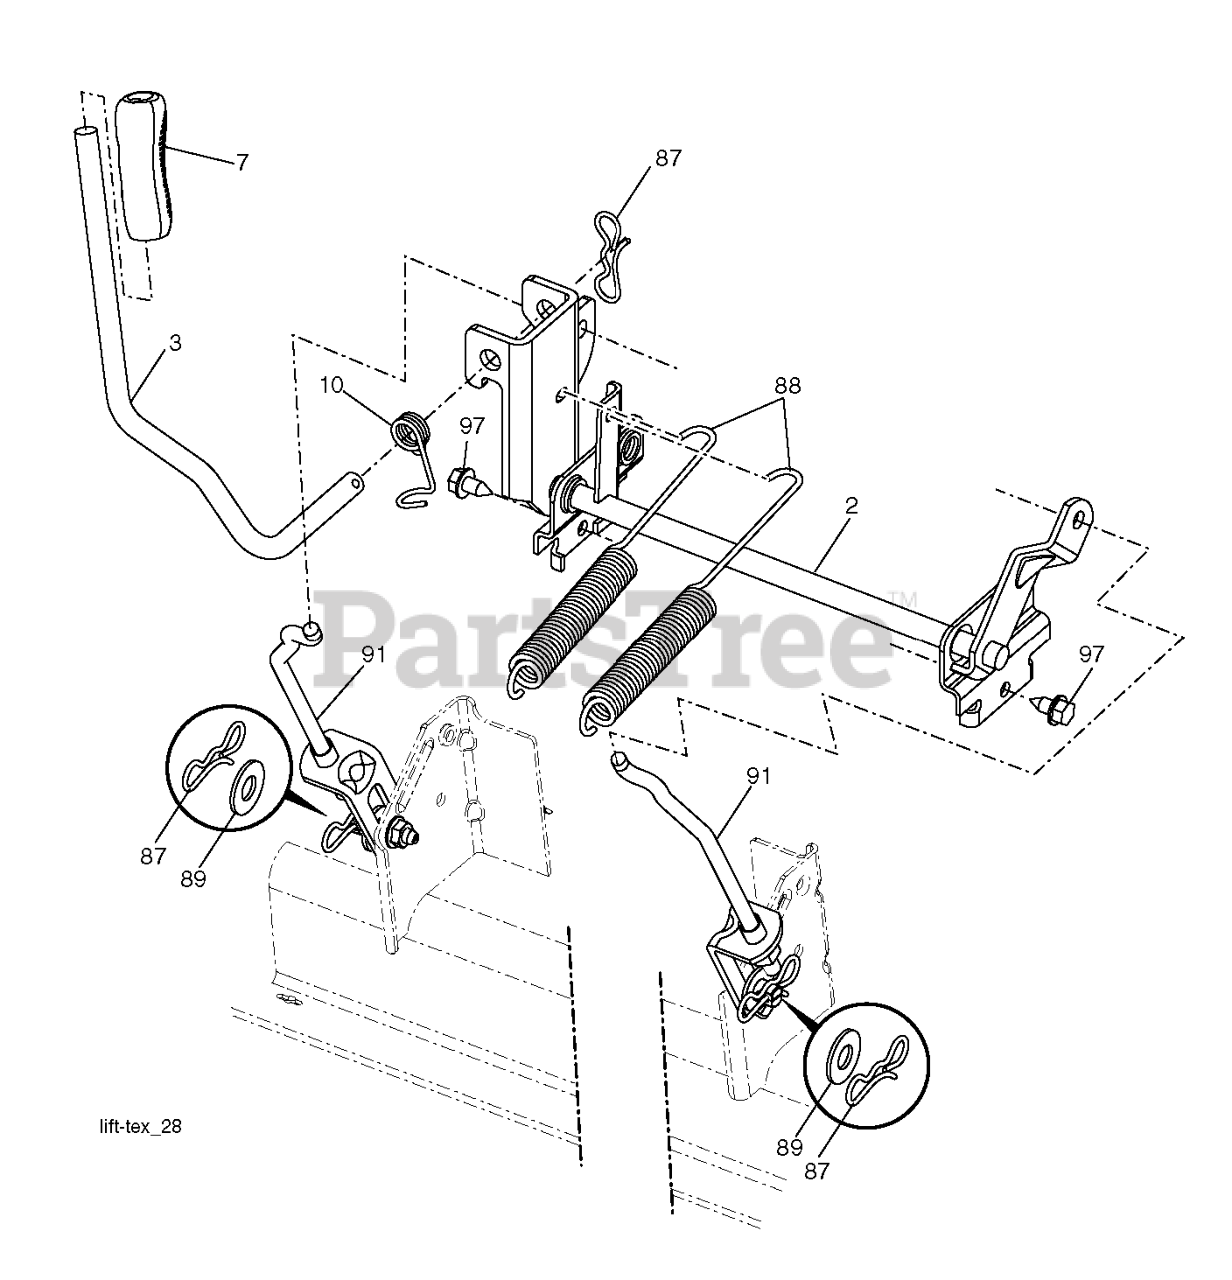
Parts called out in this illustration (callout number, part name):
2	SHAFT.ASM.CROSS.LIFT
3	LEVER.LIFT.HANDLE.LT
7	GRIP.HANDLE.LIFT.PVC.BLACK
10	SPRING.TORSION.LIFT.HANDLE
87	PIN.COTTER.7/16.BOW TI.
88	SPRING.LIFT.ASSIST
89	WASHER.CLEAR.ZINC
91	LINK.ASM.LIFT.54"TG
97	SCREW, 3/8-16X3/4
